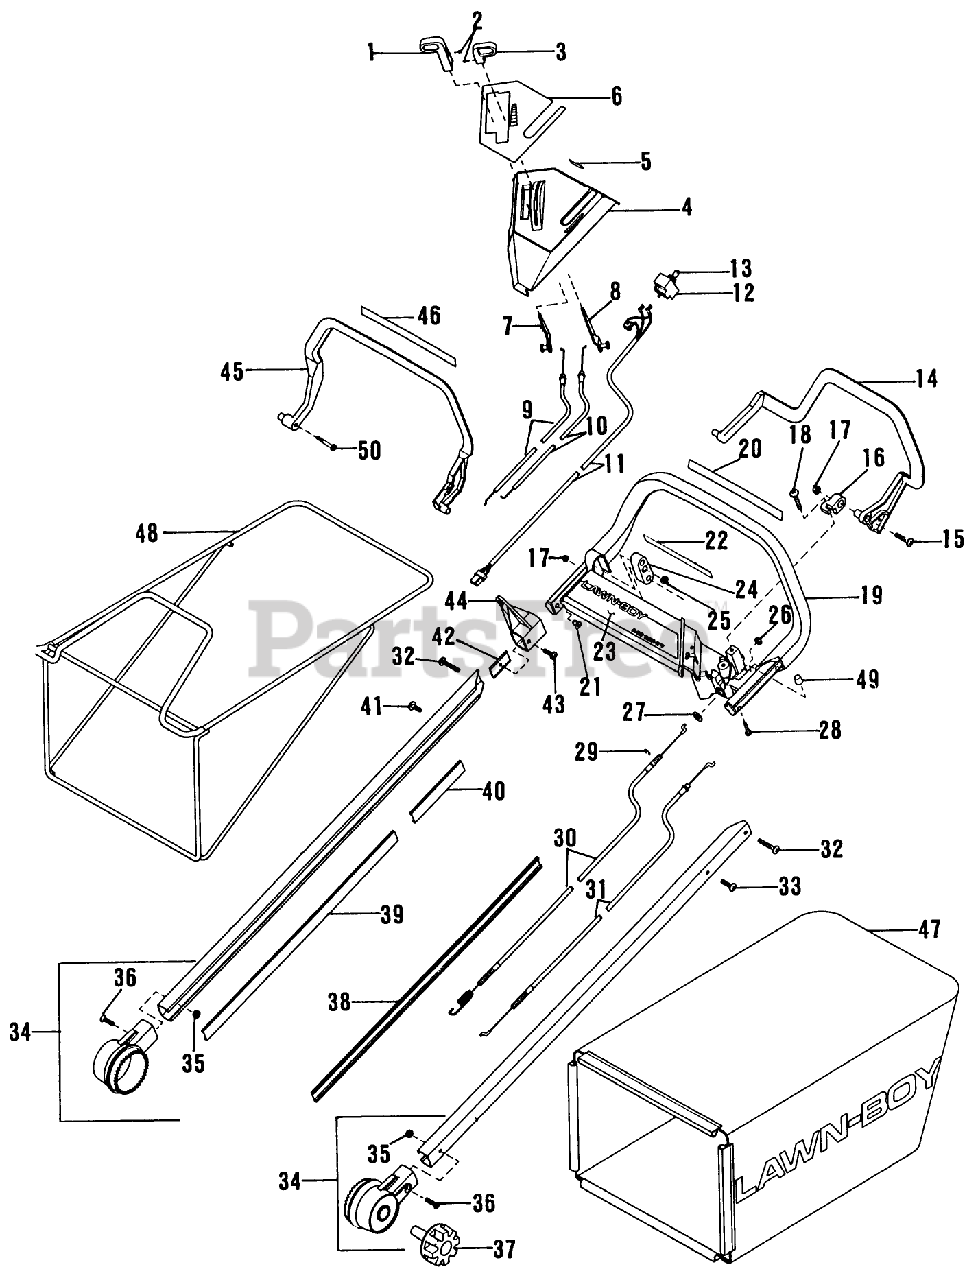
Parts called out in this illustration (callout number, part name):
4	UP.COVER &DECAL AY (12)
9	CABLE AY. WESCON
10	CABLE
14	BAIL-S.P. *
16	PIVOT BAIL PL
17	LOCKNUT FLAN
24	BLOCK BAIL PL
25	LOCKNUT E
31	CABLE ASSEMBLY
32	SCREW-TRUSS
33	SCREW-CROSS RECESS
35	LOCKNUT FLAN
37	KNOB-HDLE MT.ASM*B
42	NUT LB
47	REPL BAG FOR 684190
